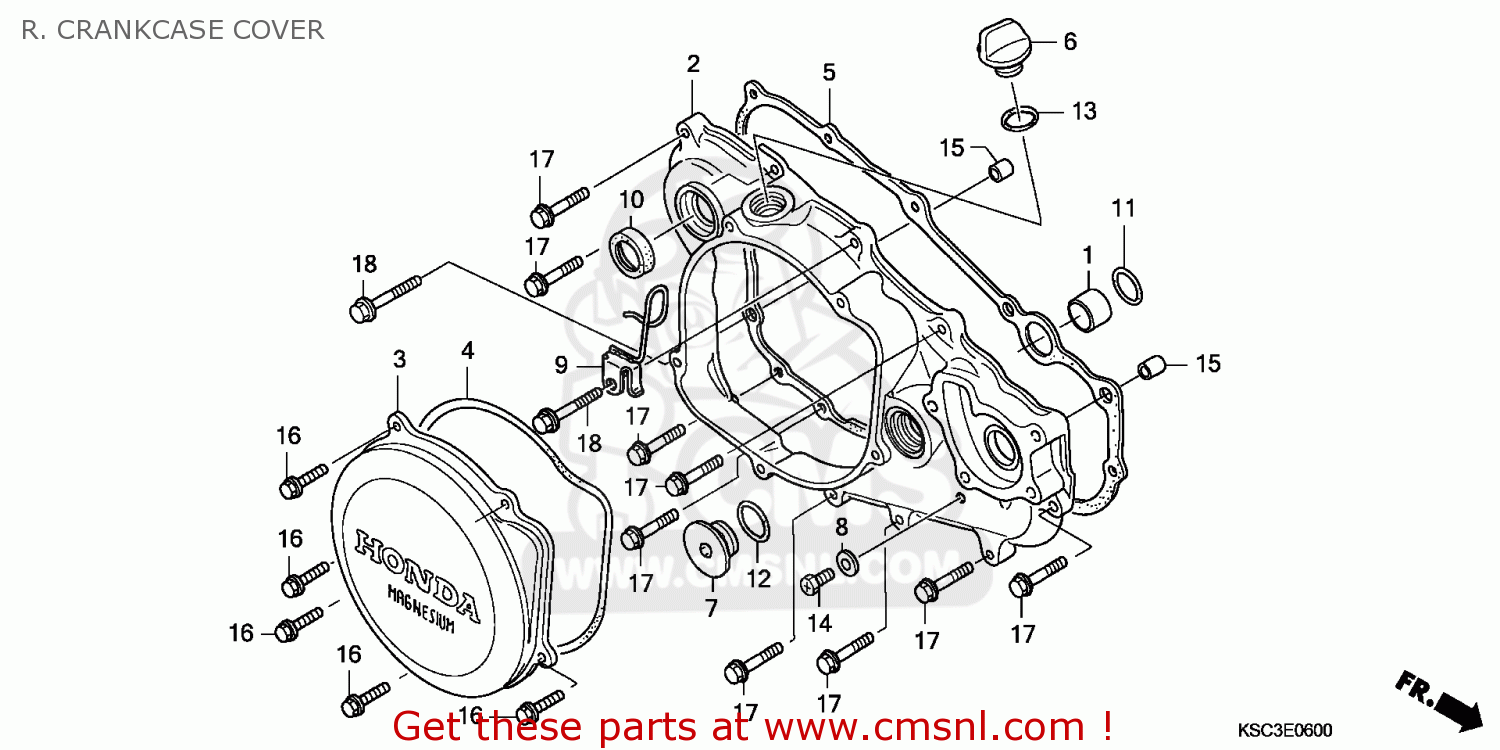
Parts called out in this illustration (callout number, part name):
1	COLLAR,WATER PASS
2	COVER,R CRANKCASE
3	COVER,CLUTCH
4	GASKET,CLUTCH COV (NAS)
5	GASKET,R COVER (NAS)
6	CAP,OIL FILLER
7	CAP,30MM
8	WASHER,SEALING,6.
9	GUIDE COMP,CLUTCH
10	OIL SEAL16.5X25X5
11	O-RING
12	O-RING,27X2
13	O-RING,11.9X2.2
14	BOLT,FLANGE,NSHF,
16	BOLT FLANG 6X20
17	BOLT,FLANGE,6X28
18	BOLT,FLANGE,6X35
